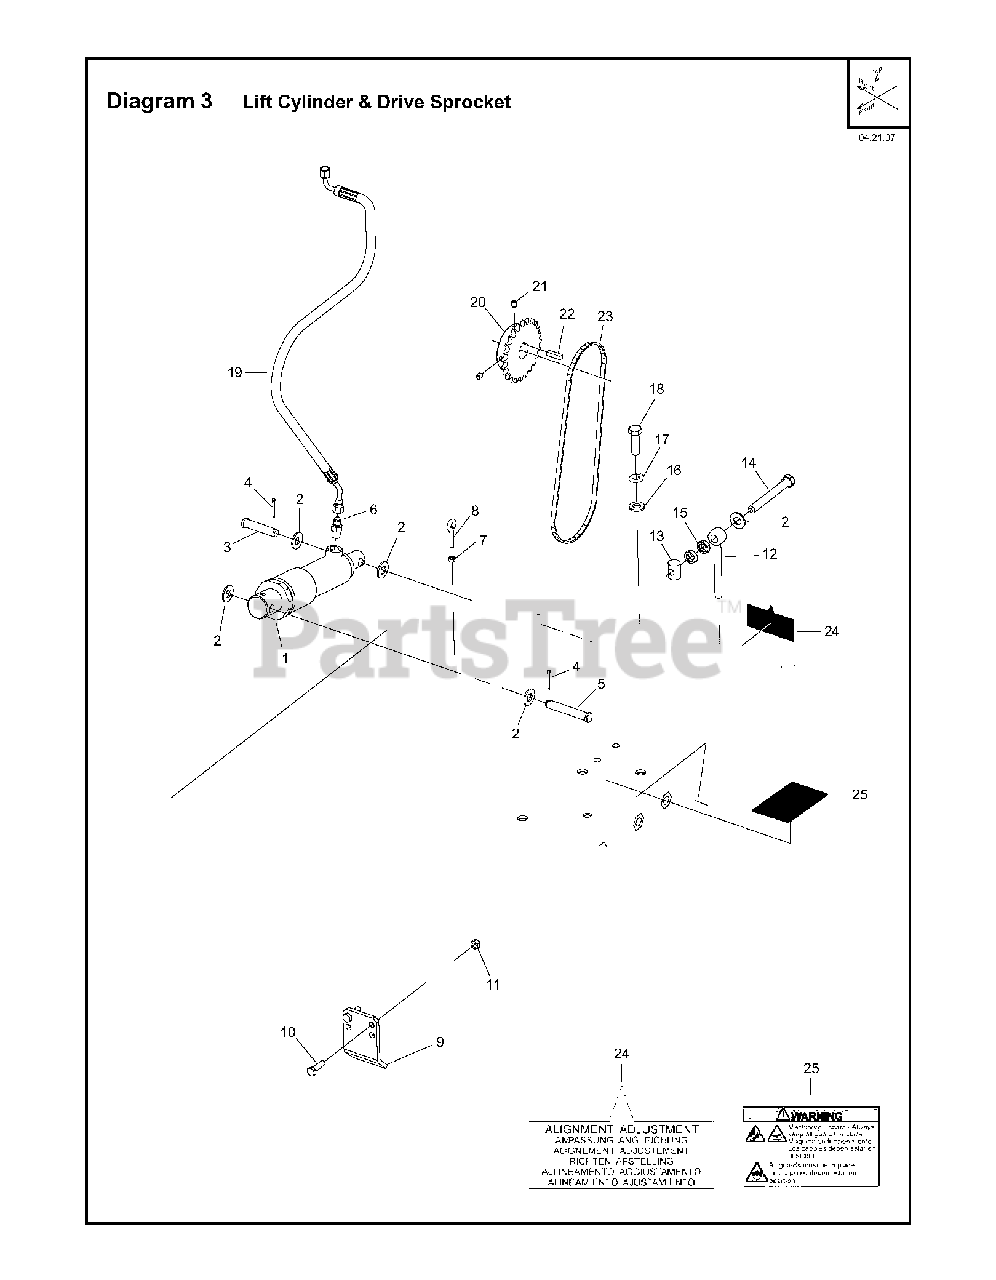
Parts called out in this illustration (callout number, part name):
1	CYLINDER
4	PIN. COTTER .125 x 1
7	NUT
8	EYEBOLT. M6x1.0x50mm OAL
11	LOCKNUT. FIBER M8 DIN 985 Z/P
12	PIN. GUIDE
13	SWIVEL. M12 x 1.75.BLACK OR ZP
14	HHCS M12x1.75x100 DIN 933ZP
16	WASHER
17	LOCKWASHER. SPLIT M12 DIN 127
21	SHSS. .3125-18 X .375
22	KEY. 1/4 Sq. x 1
23	CHAIN. #40 ROLLER 62 PITCHES
24	ALIGNMENT ADJ DECAL (DB)
